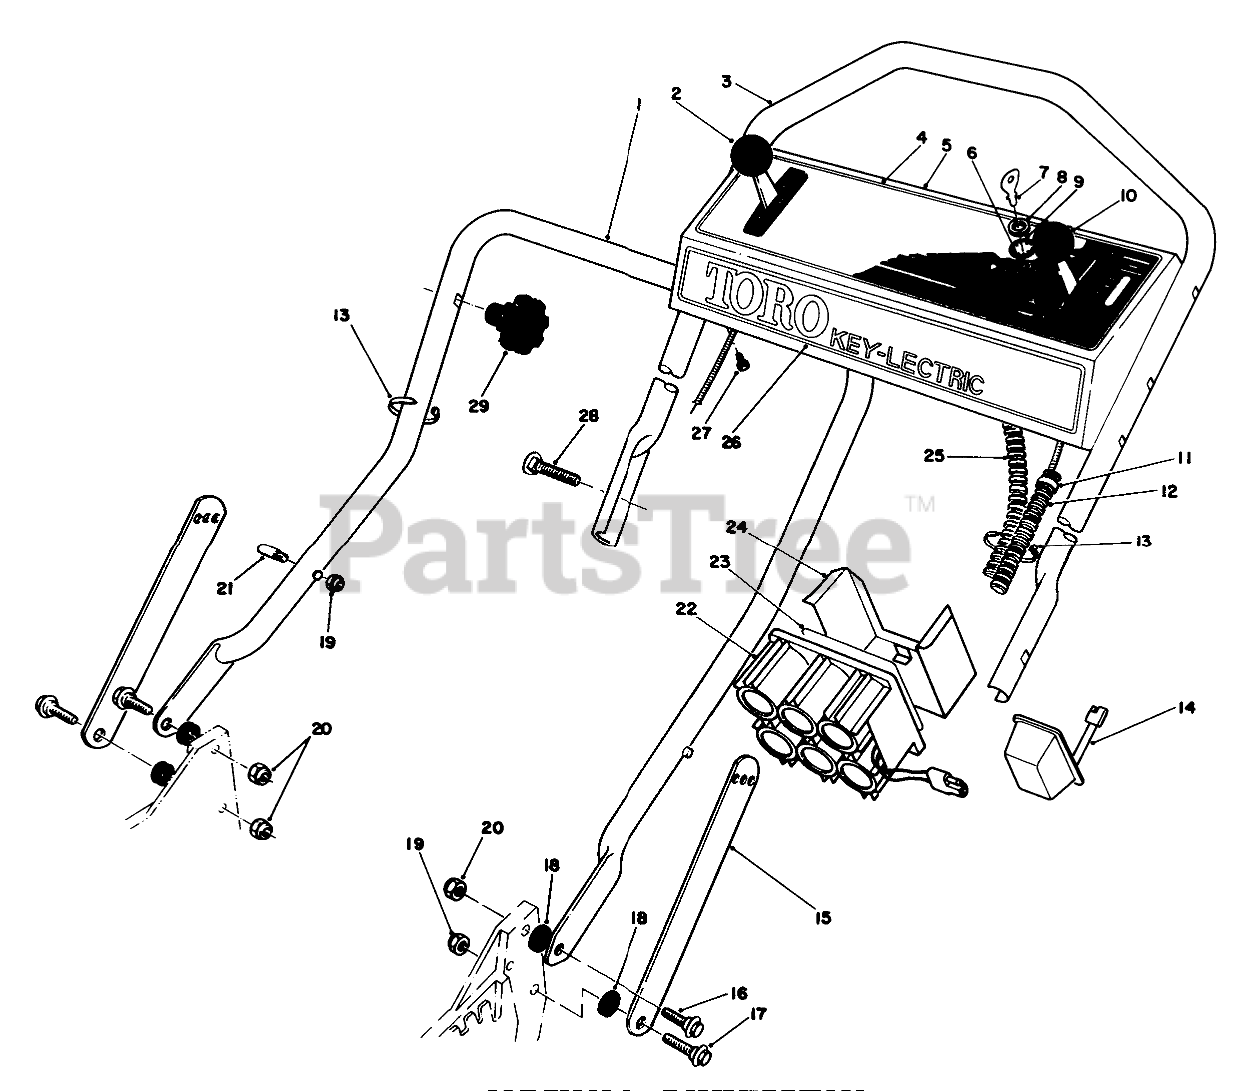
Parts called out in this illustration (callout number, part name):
1	LOWER HANDLE ASM
2	SERVICE THROTTLE CONTRO
3	Handle-Upper
4	INST PANEL DECAL
5	Panel-Control (Incl. Ref. #4)
6	Switch-Starter (Incl. Ref. #8-9)
7	Key
8	NUT-HH
9	WASHER-TOOTH, INTERNAL
10	SERVICE TRACT. CONTROL
11	FITTING-RING
12	CONTROL CABLE COVER
13	TIE-CABLE
14	Charger
15	Handle Latch
16	SCREW-SHOULDER
17	SCREW-SHOULDER
18	SPACER
19	NUT-LOCK, NI
20	NUT-LOCK, NI
21	HANDLE PIN
22	BATTERY ASSEMBLY
23	Decal
24	Retainer-Battery
25	WIRE HARNESS
26	Decal-Toro
27	SCREW-HWHTF
28	5/16-18 X 2 HNDLE SCREW
